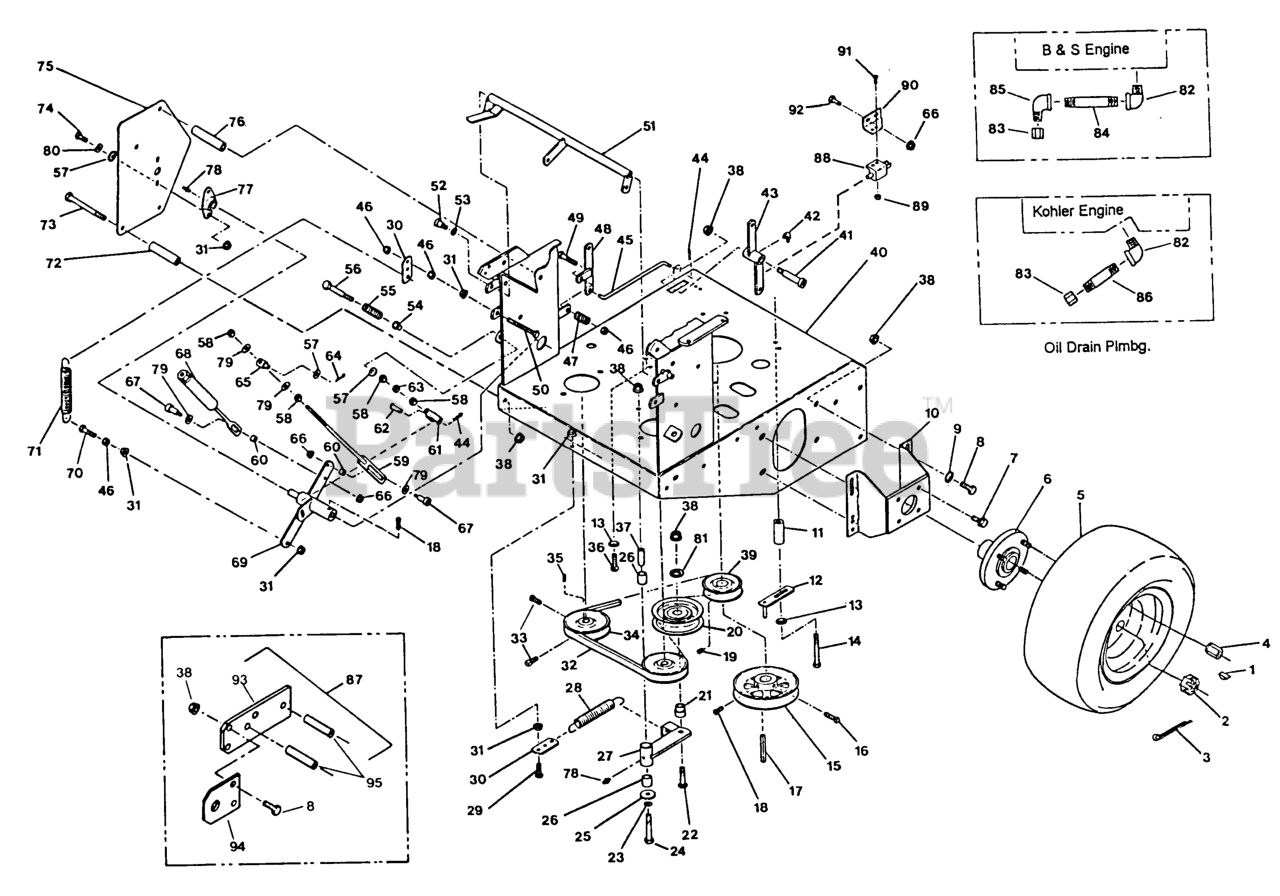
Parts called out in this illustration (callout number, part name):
1	KEY-WOODRUFF
3	PIN-COTTER
12	GUIDE-BELT
13	WASHER-SPRING
14	SCRW,CAP HH M8X1.25X75M
17	KEY,MACH 1/4X1/4X2-5/8
18	SCREW-SET
19	SCREW-SET
21	BUSHING-IDLER
26	SLEEVE-BEARING
27	IDLER ARM ASM
28	SPRING-EXTENSION
30	ANCHOR-SPRING
32	BELT,HYDRO TRANS DRIVE
33	SCREW-SET
34	SHEAVE - PUMP
37	BUSHING
43	BELLCRANK ASM
44	PIN-COTTER
45	LINKAGE-ENGAGE, BLADE
47	SPRING-COMPRESSION
50	BOLT,TAP HH
52	SCREW-HSH
54	BUSHING-FLANGED
55	SPRING-RETURN, NEUTRAL
56	BOLT-RETURN, NEUTRAL
61	YOKE-ADJUSTABLE
62	PIN-CLEVIS
67	SCREW-HSH
69	WLD,HYDRO CONTROL ARM LH
71	SPRING-EXTENSION
72	SPACER-SHIELD
76	SPACER-SHIELD
77	FLANGE MTG, SIDE
80	WASHER-LOCK
82	FITTING-ELBOW-90
83	CAP-HEX
84	NIPPLE
85	ELBOW-90 DEG
86	NIPPLE
87	Sulky Hitch Kit - Vik Hydro
88	SWITCH-OPEN, NORMALLY
90	BRACKET-SWITCH, BLADE
93	MOUNT-HITCH
94	Bracket, Hitch Adapter
